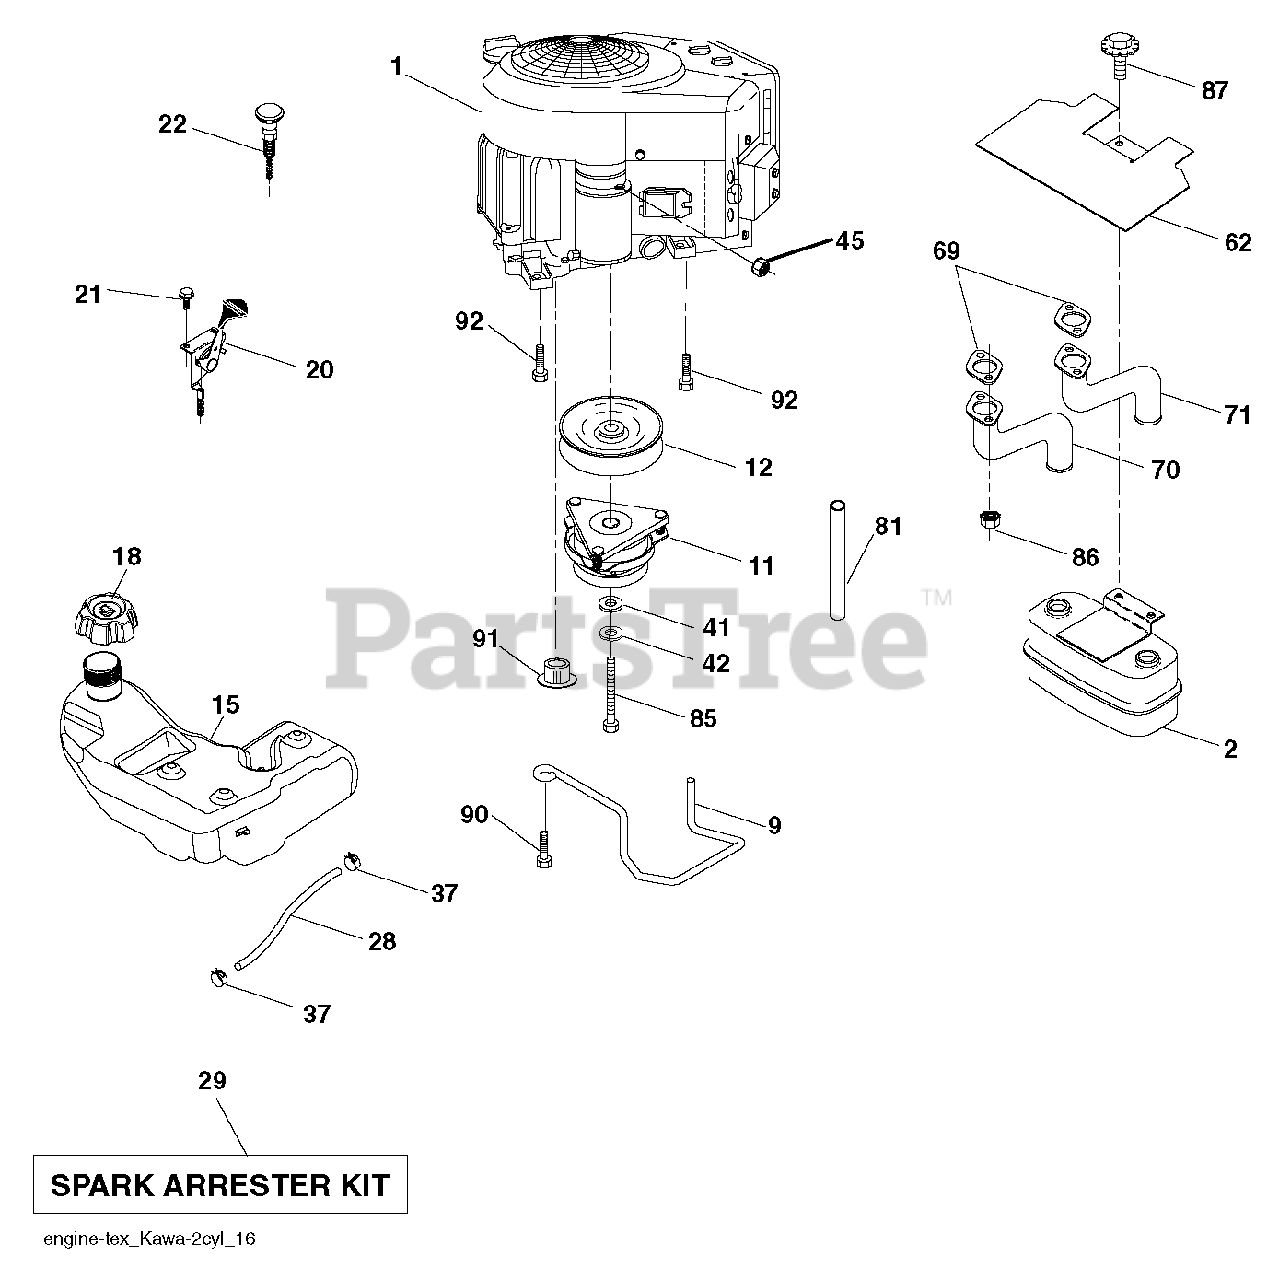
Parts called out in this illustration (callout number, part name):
1	Husqvarna TBD
2	MUFFLER.TWIN.CYL.LOW.TONE
9	KEEPER.BELT.ENGINE.4.2
11	CLUTCH MZ ZTR GT.48/54"1.125"
12	PULLEY ENGINE
15	TANK.FUEL.4GAL
18	CAP.FL.R.3'N/CARB.H.CROWN.498
20	THROTTLE CONTROL
21	SCREW.#10 X 0.750.BOS
22	CONTROL.CHOKE.ERGO.PUSH-IN.BLA
28	REPL BY 532 00 85-43
29	KIT.SPARK ARRESTOR 794945 B&S
37	HOSE CLAMP
42	LOCKWASHER
45	NUT
62	SHIELD.HEAT.MUFFLER
70	TUBE.EXHAUST.LH.FR961/FR730
71	TUBE.EXHAUST.RH.FR961/FR730
81	TUBE, DRAIN OIL ASM.
85	BOLT HEX 7/16-20 X 3.75 GR. 5
86	NUT.HEX.FLANGE.TOPLOCK
87	BOLT.5/16-18UNCX1.W/SEMS.BLK
90	SCREW 3/8-16X1
91	BUSHING.1.375OD
92	SCREW 3/8-16X1
